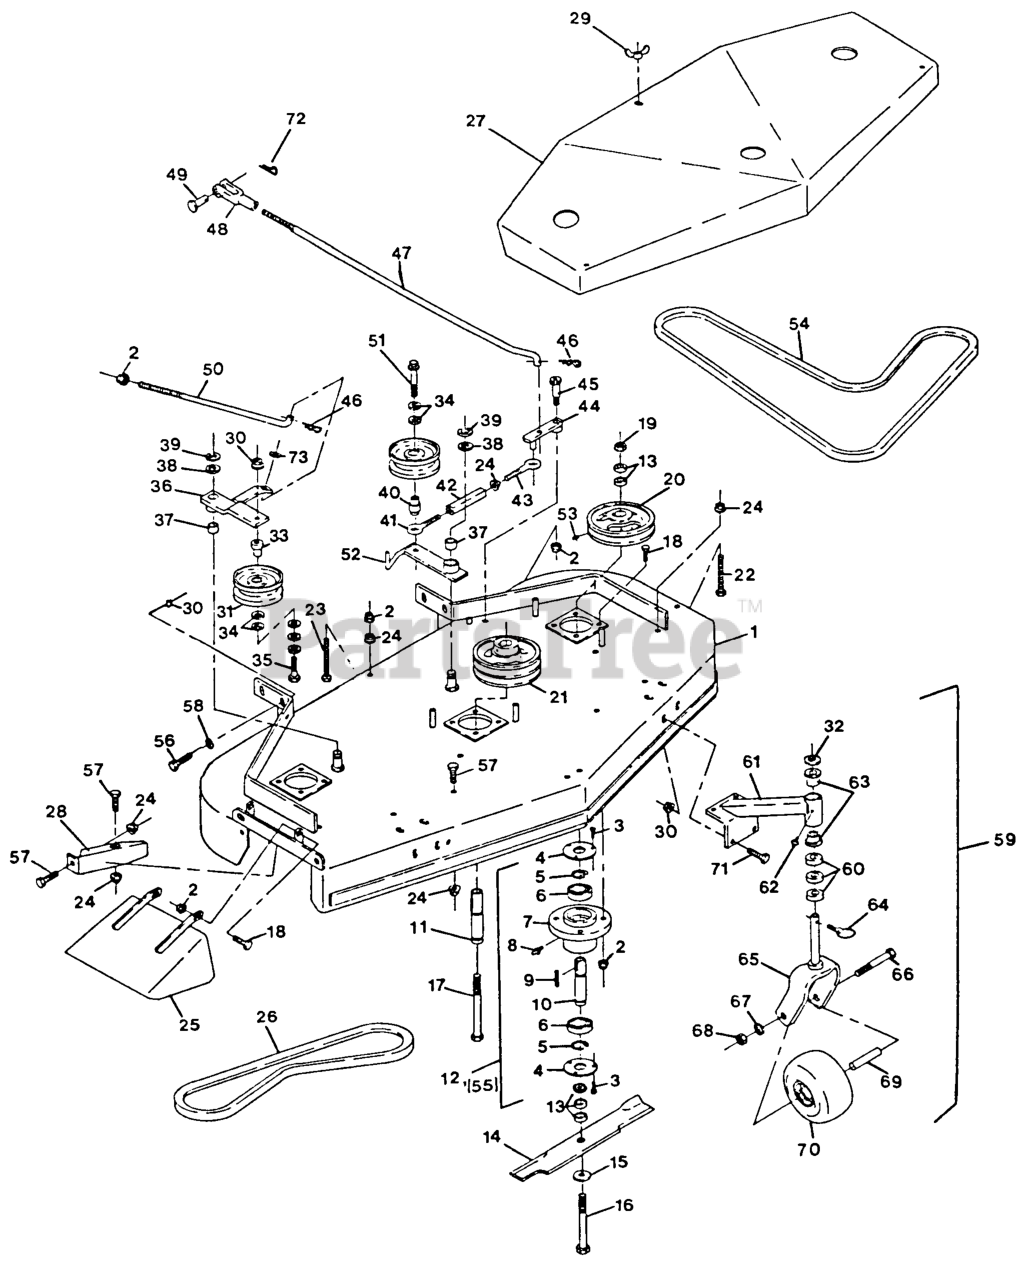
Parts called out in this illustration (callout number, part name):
3	SCRWMACH PHS
4	CAP,CUTTER HOUSING
5	RING,RETNG WLDS 5108-100
7	HOUSING,CUTTER
10	SPINDLE,CUTTER
12	HOUSING,CUTTER COMPLETE
17	SCREW-CAP, HH
20	PULLEY,CAST IRON
22	BOLT,TAP HH
23	BOLTTAP HH
26	BELT,FRONT DECK
28	BAFFLE-DOGLEG
32	WASHER-FLAT
33	BUSHING-IDLER
36	ARM,IDLER COMPLETE
37	BEARING,POWDERED METAL
38	WASHER-SPINDLE
40	BUSHING-ENGAGEMENT
41	EYEBOLT-THREAD, LH
42	BODY-TURNBUCKLE
43	EYEBOLT-THREAD, RH
45	BOLT,SHLDR KSKH
46	PIN-COTTER
47	ARM-LINKAGE, ASSIST
48	YOKE-ADJUSTABLE
49	PIN-CLEVIS
50	ROD,BELT TENSION
53	SCREW-SET
54	BELT,BLADE DRIVE 36
55	HOUSING,CUTTER COMPLETE
60	SPACER-CASTER
63	BEARING-FLANGED
